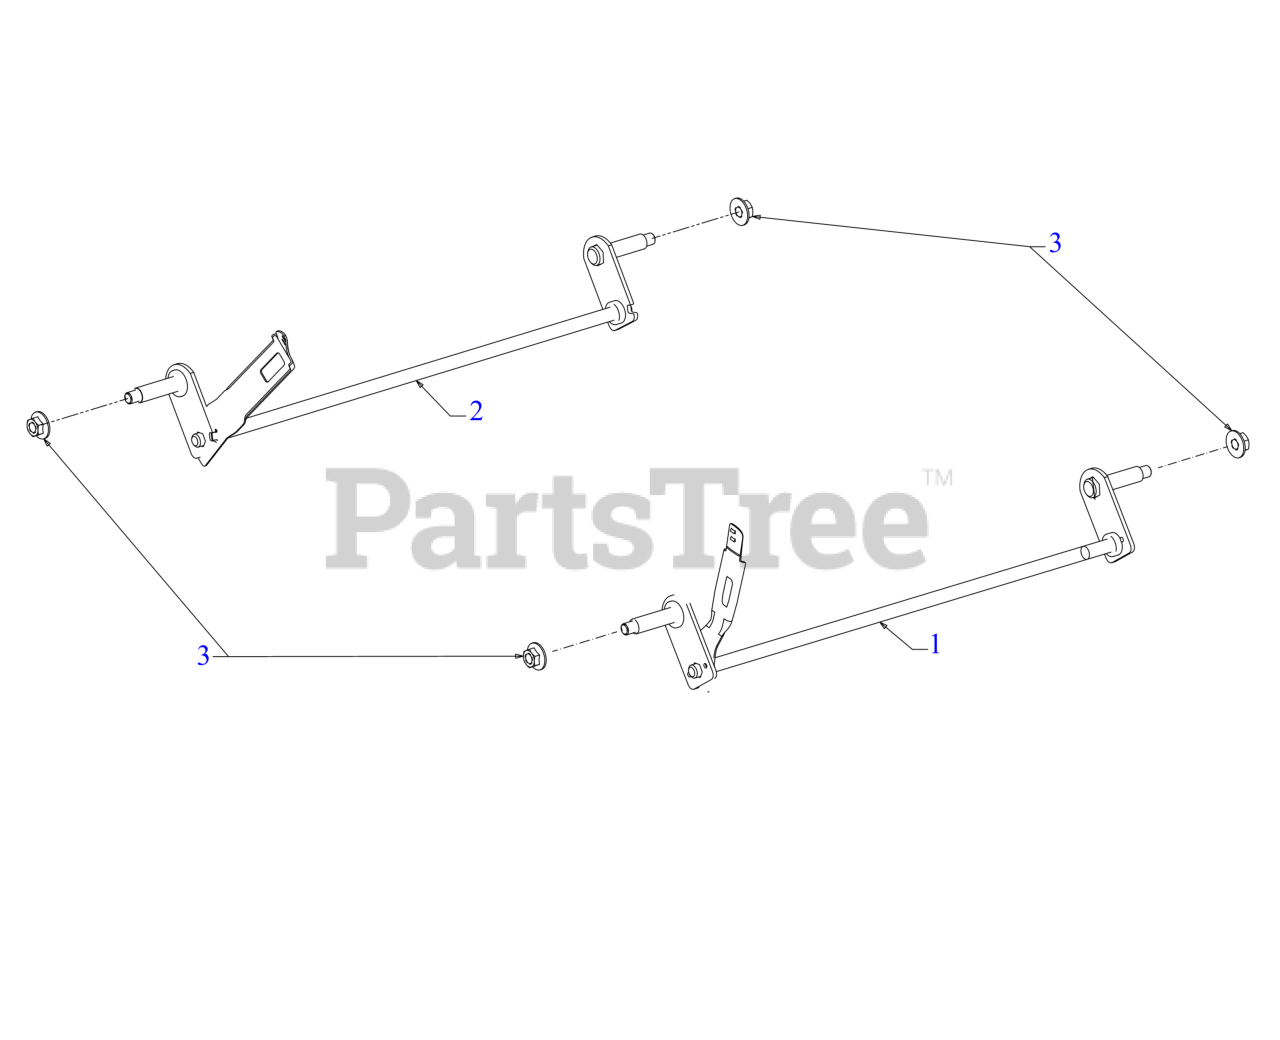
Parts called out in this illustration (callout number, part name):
1	7" FRONT AXLE ASSEMBLY
2	8" REAR AXLE ASSEMBLY
3	FLANGE LOCK NUT
